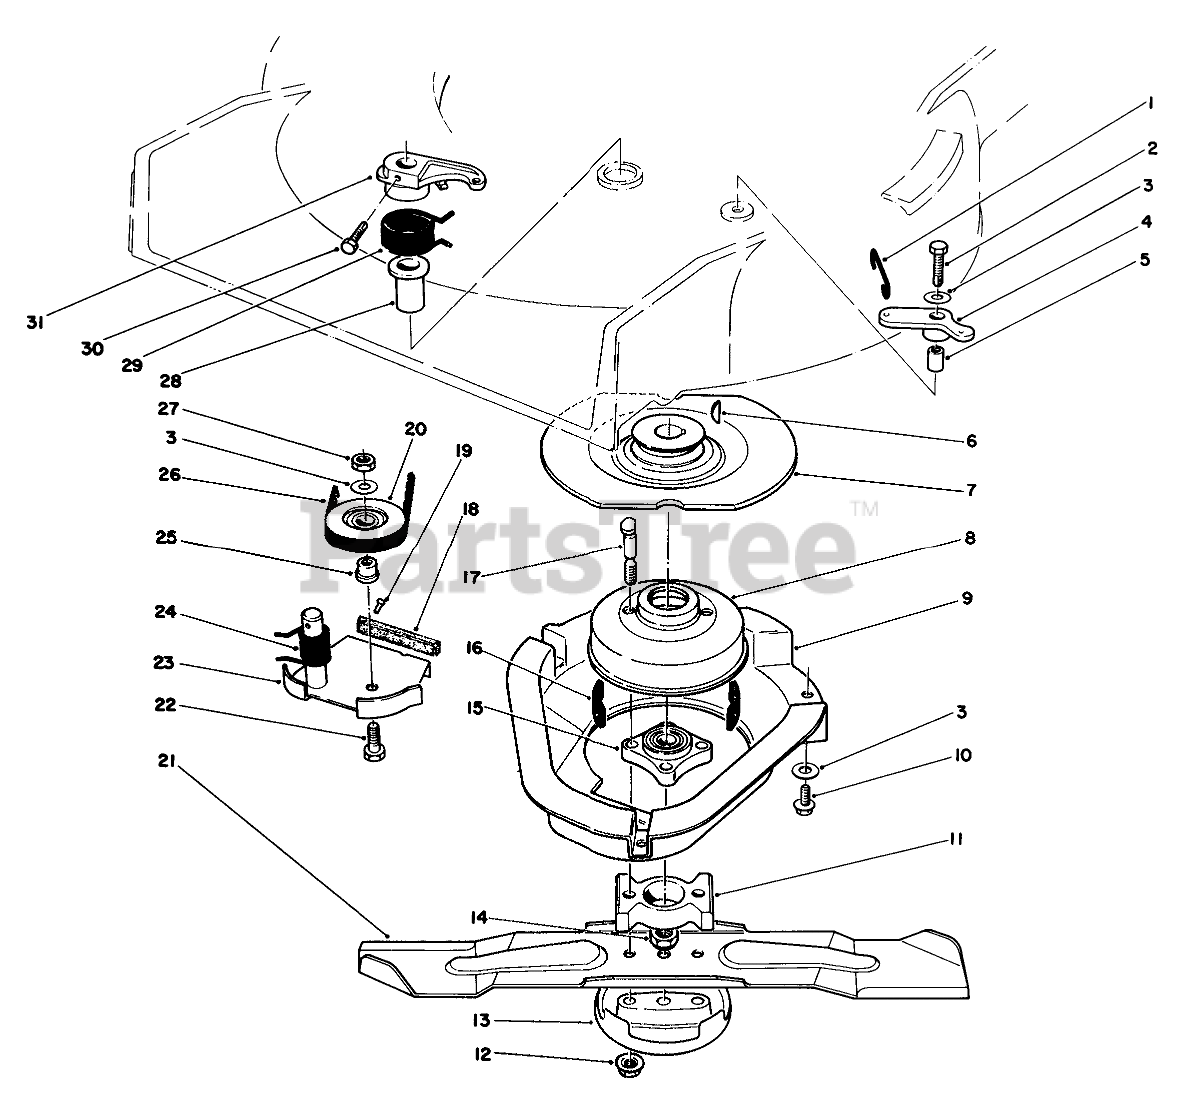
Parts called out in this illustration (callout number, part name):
1	LINK-CONTROL
2	SCREW-HH
3	WASHER-PLAIN
4	BELLCRANK
5	SLEEVE-BELLCRANK
6	KEY-WOODRUFF
7	Flywheel
8	Brake Drum
9	SHIELD BBC
10	SCREW-HWHTF
11	Spacer Blade
12	NUT-LOCK
13	Anti Scalp Cup
14	NUT-LOCK, NI
15	HUB ASM
16	DAMPENER-VIBRATION
17	BOLT-BLADE
18	Pad-Brake
19	.185 DIA X .375 RT +
20	PULLEY-IDLER
21	BLADE-21in
22	SCREW-HH
23	Brake Plate (Incl. Ref. #18 & 19)
24	SPRING-TORSION
25	HUB-PULLEY, IDLER
26	V-BELT
27	NUT-LOCK, NI
28	BUSHING PM
29	SPRING-TORSION
30	SCREW-HH
31	LEVER
